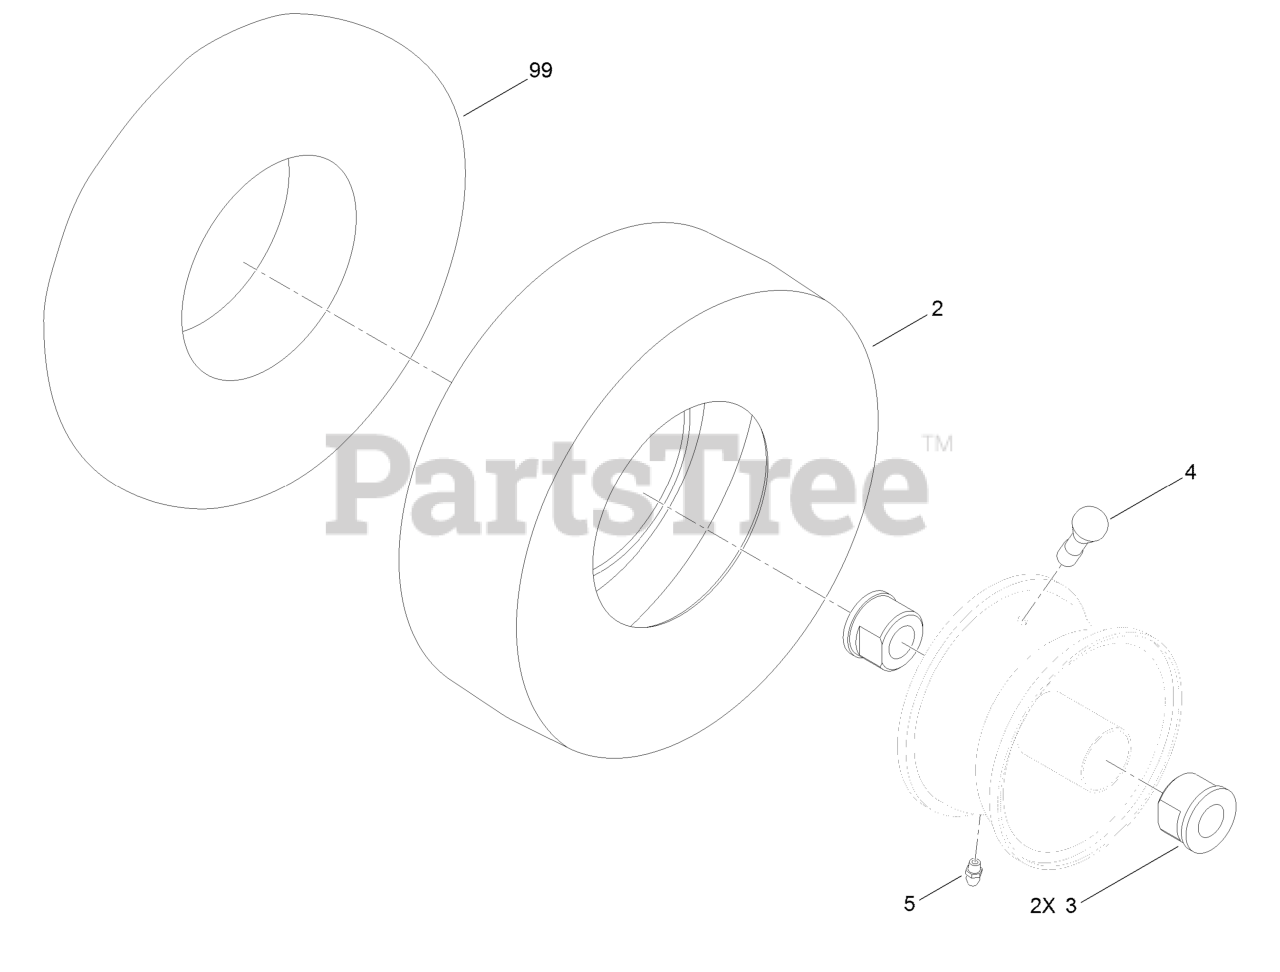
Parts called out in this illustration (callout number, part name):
3	Bushing-Flange
4	Stem-Valve
5	Fitting-Grease
99	Tube-Inner
